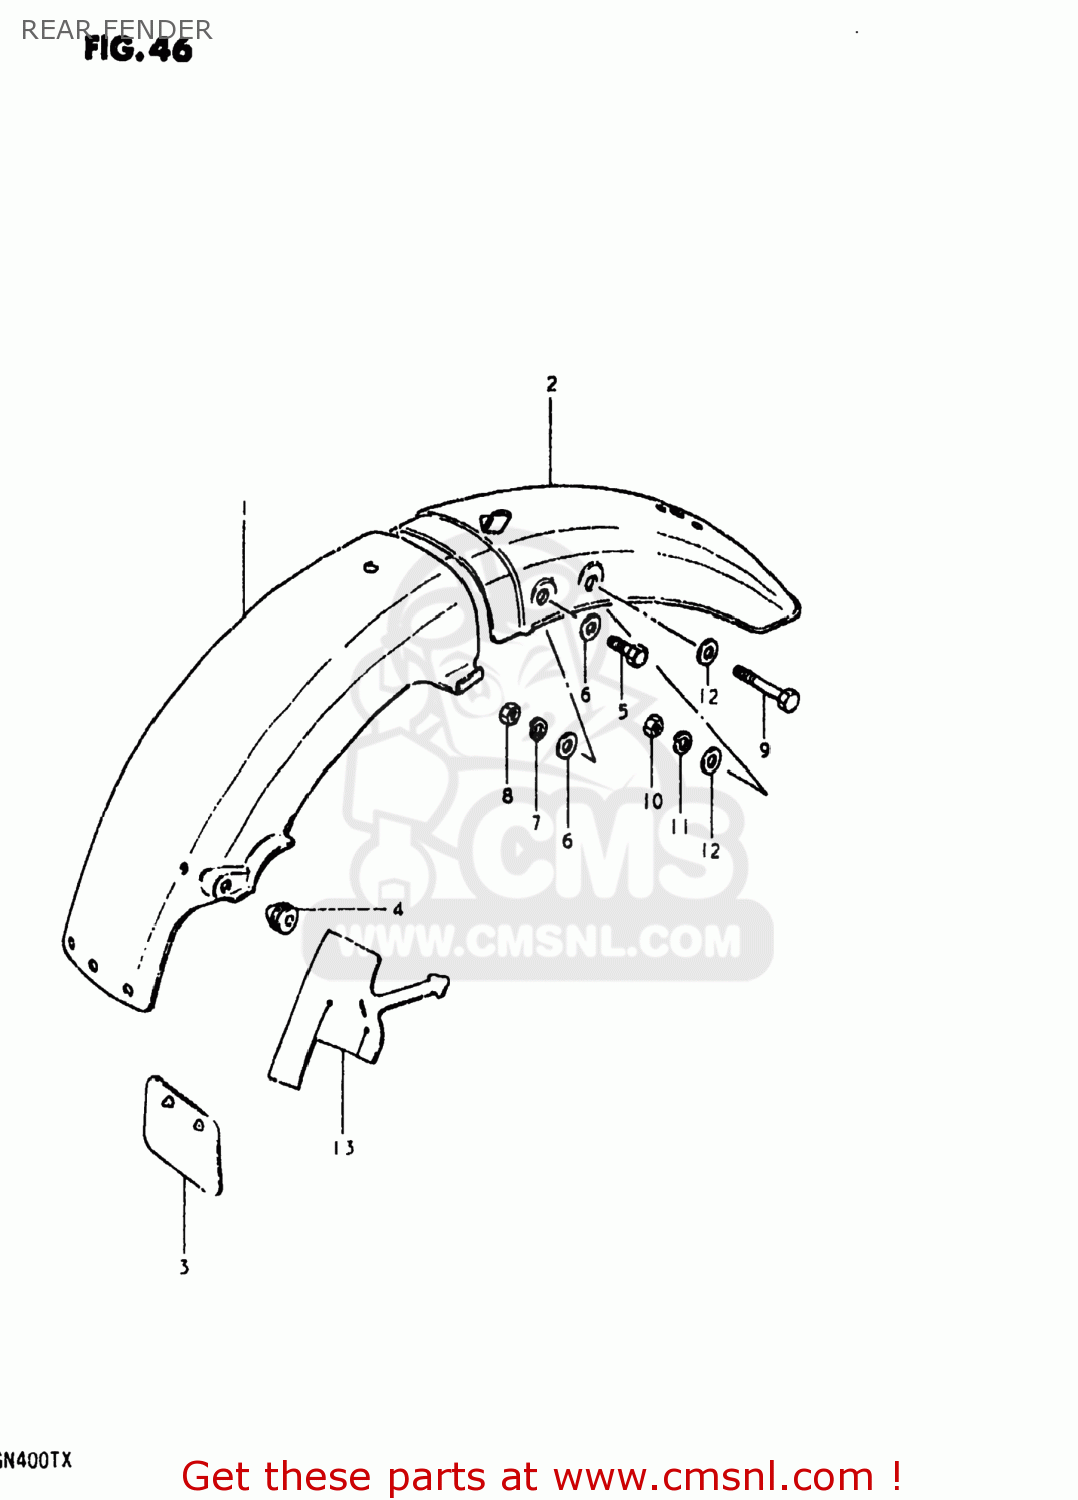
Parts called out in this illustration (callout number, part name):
1	FENDER,REAR
2	FENDER,REAR
3	MUD GUARD,REAR FENDER
4	CUSHION,REAR FENDER,FRONT
5	BOLT
6	WASHER
7	LOCK WASHER
8	NUT 8MM
9	BOLT
10	NUT 8MM
11	LOCK WASHER
12	WASHER
13	MUD GUARD,REAR FENDER
